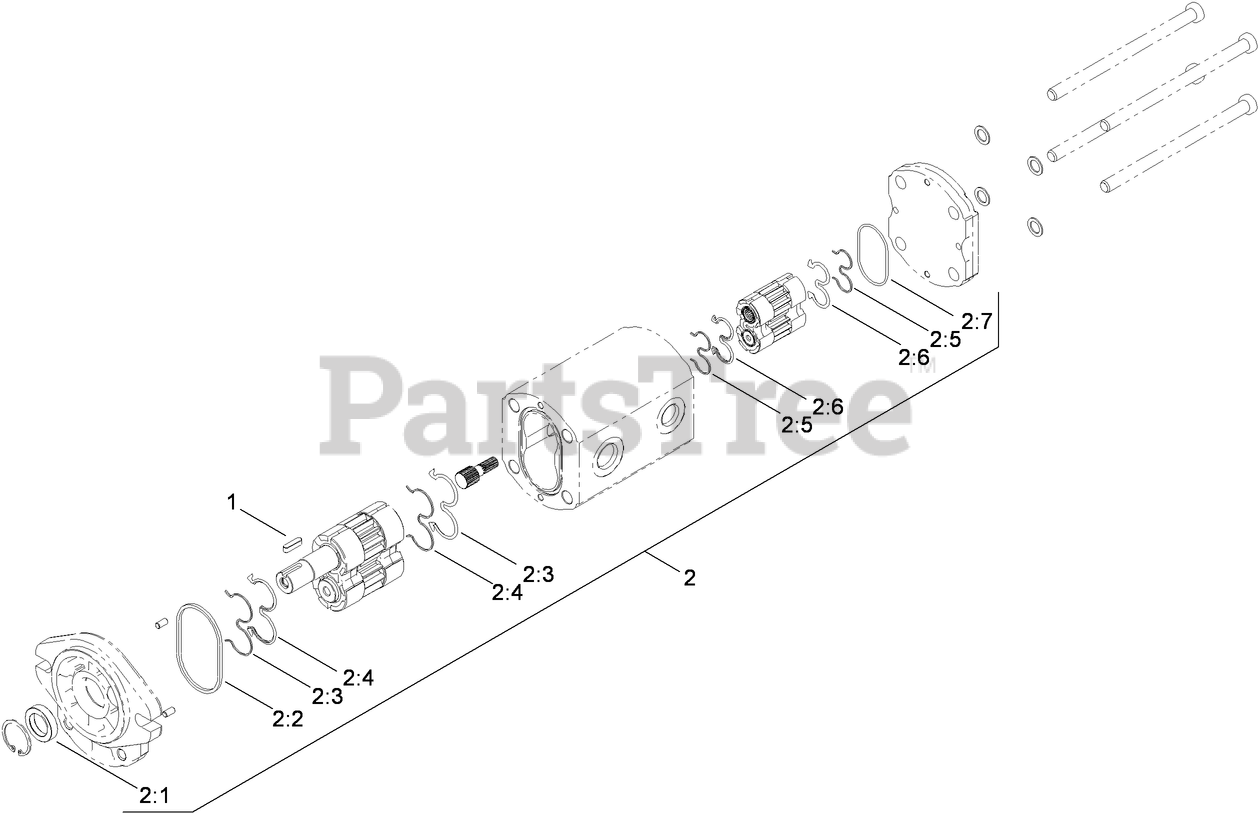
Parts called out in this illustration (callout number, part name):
1	KEY-SQUARE
2	SEAL KIT
2:1	SEAL-SHAFT
2:2	SEAL-SQUARE
2:3	RING-BACKUP
2:4	SEAL-GEAR
2:5	RING-BACKUP
2:6	SEAL-GEAR, REAR
2:7	O-RING
